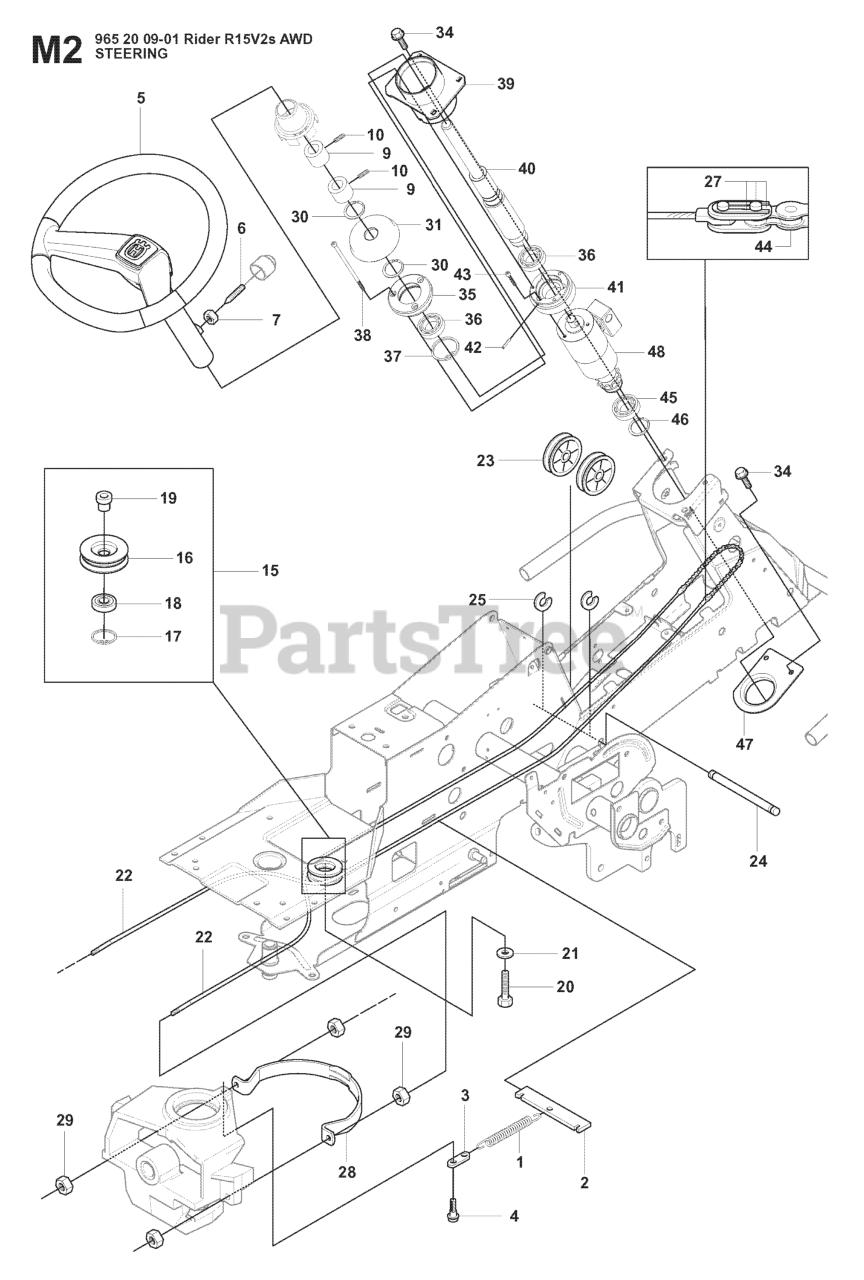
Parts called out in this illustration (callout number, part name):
2	SPRING BRACKET
7	NUT
9	SPACER
17	CIRCLIP SGH 47
18	BALL-BEARING 6204-2RS
22	RP STEERING CABLE COMPLETE
25	RETAINING RING
28	WIRE GUIDE
29	NUT
30	RETAINING RING SGA 25
36	Ball Bearing 6005-2rs
37	CIRCLIP SGH 47
38	SCREW IHSCM.
42	SPRING PIN
43	SCREW MC6S 6X20
